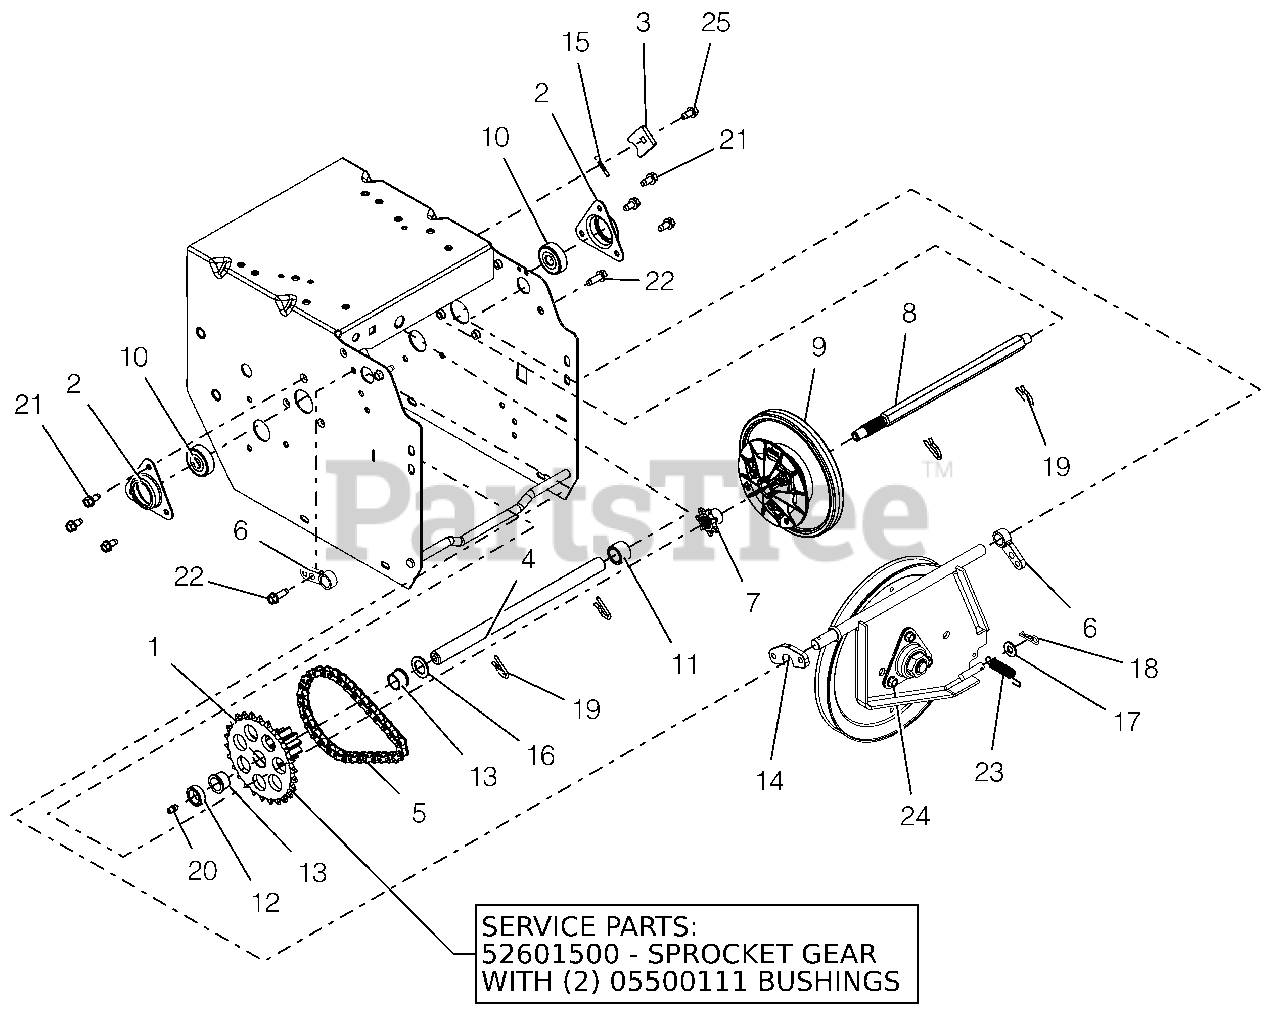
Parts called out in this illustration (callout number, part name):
1	PINION & SPROCKET
1	PINION & SPROCKET W/BUSHINGS
1	BSHG-FLG .625X.750X.500X.875
2	FLANGE, BEARING
3	TAB, ANTI ROTATION
4	SHAFT, PINION
5	CHAIN - #41, 32 PITCHES
6	SUPPORT BUSHING, SWING GATE
7	SPROCKET, PINION 7T W/SPLINE
8	SHAFT, HEX W/SPLINE
9	DISC, FRICTION DRIVE-ASSEMBLY
10	BRG-BALL .437X1.375X.437
11	SPACER, .635X.880X.611
12	BSHG-SLV, .635X.880X.305
13	BSHG-FLG .625X.750X.500X.875
14	SPACER, SWING GATE
15	PIN-GRV .125X1.00 TP E ALLOY
16	WSHR-FL-STL .630X1.005X.062 YZ
17	@WSHR-FL-STL.344X.688X.065YWZC
18	PIN-HAIR INT .08X.18X1.18 YWZC
19	PIN, SPRING CLIP
20	ZERK,FITTING .25X.125 DRIVE IN
21	SCR-TAP .25-20X.50 HWH TR YWZ
22	SCR-TAP-PM .25-20X.75 TR YWZ
23	SPRING, EXT. .043X.438X1.64
24	PLATE, SWING - ASSEMBLY
25	SCR-TAP .25-20X.50 HWH TR YWZ
